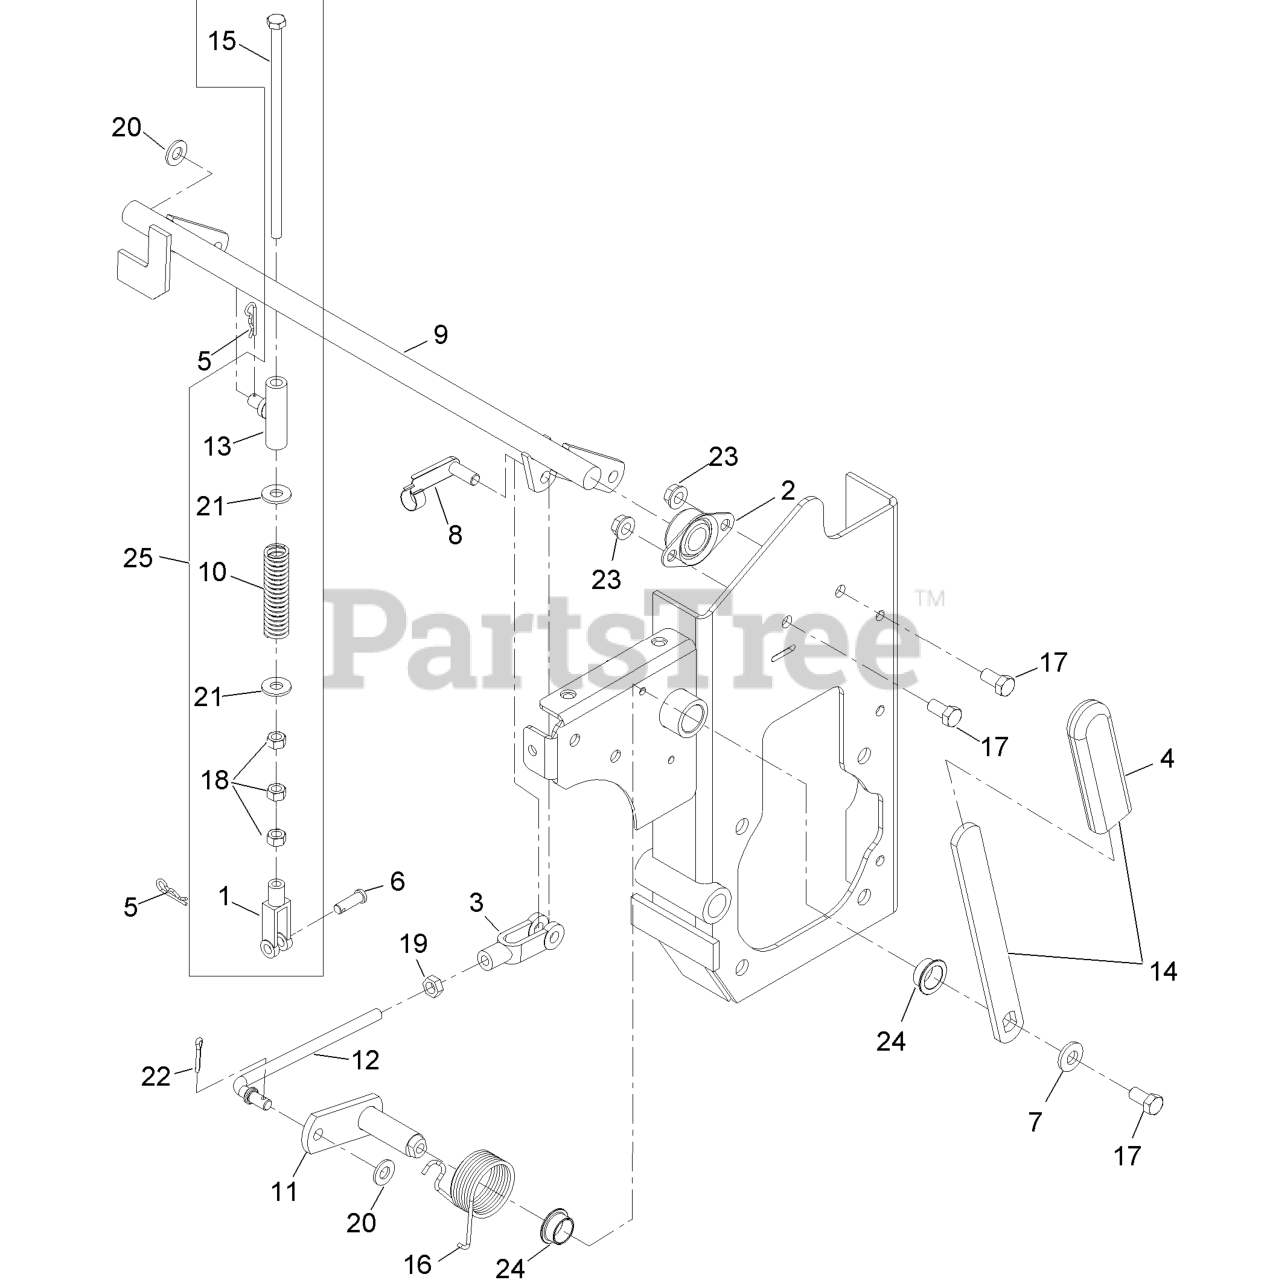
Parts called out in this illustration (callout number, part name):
1	YOKE-ADJUSTABLE
2	BEARING-FLANGE, SIDE
3	YOKE-LINKAGE, BRAKE
4	GRIP-LEVER
5	PIN-COTTER
6	PIN-CLEVIS
7	WASHER-BELLEVILLE
8	PIN-SPRING, CLEVIS
9	WLD, BRAKESHAFT
10	SPRING,COMPRESSION
11	WLD,BRAKE PIVOT (PLATED)
12	ROD,LINKAGE BRAKE (PLATED
13	WLD,SWIVEL BRAKE (PLATED)
14	PARK BRAKE HANDLE ASM
15	SCREW-HH
16	SPRING,TORSION RH
17	SCREW-HH
18	NUT-HEX
19	NUT-HEX
20	WASHER-FLAT
21	WASHER-FLAT
22	PIN-COTTER
23	NUT-HHF, WHIZ
24	BUSHING-BRONZE
25	ASM,BRAKE LINKAGE
